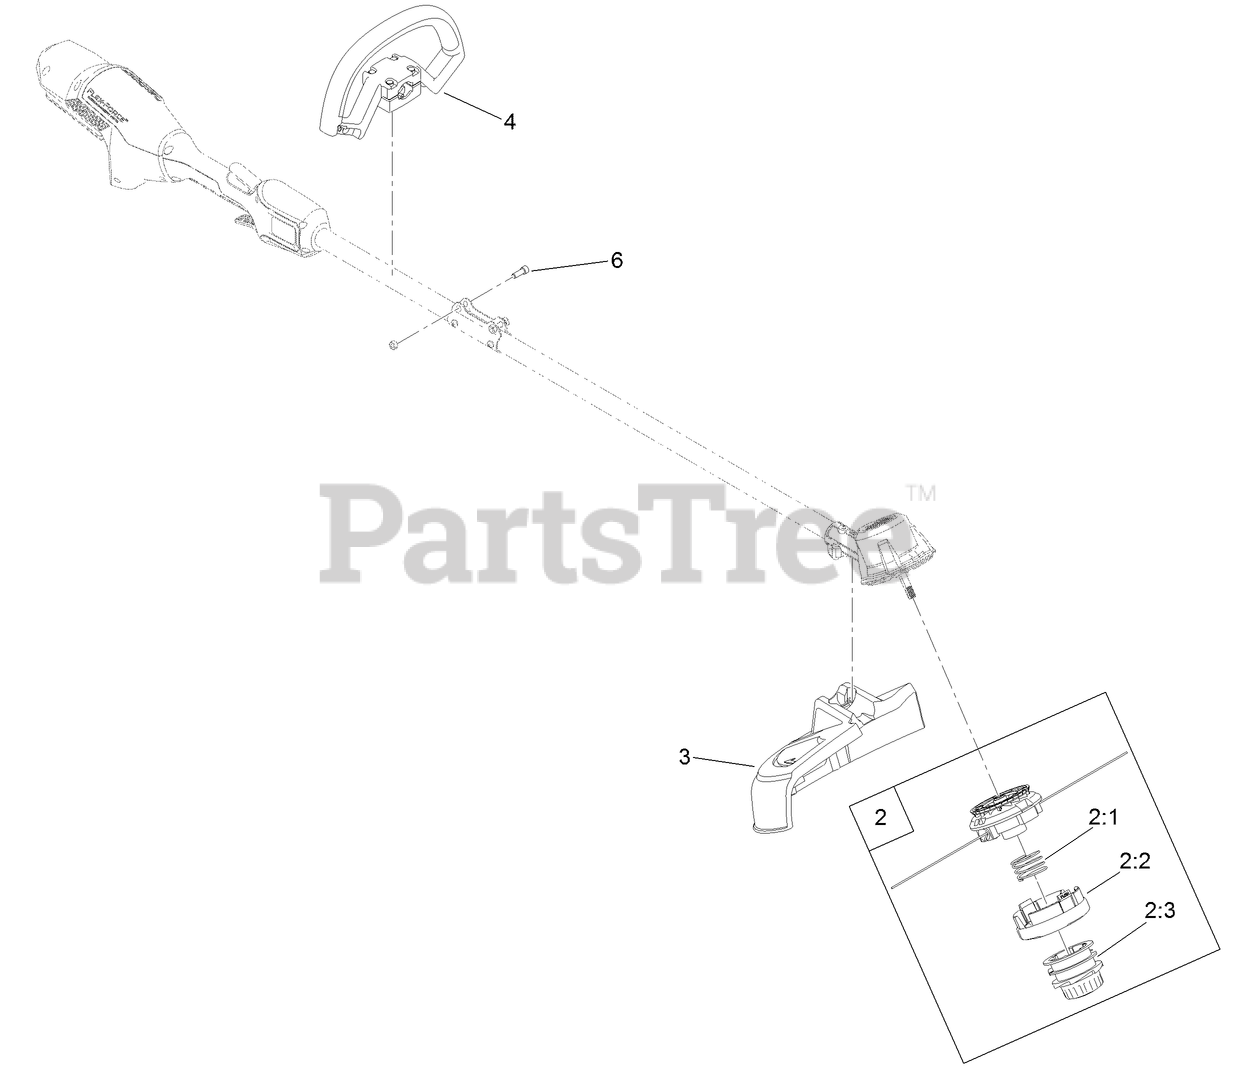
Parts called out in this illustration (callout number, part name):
2	BUMP FEED HEAD ASM
2:1	SPRING-SPOOL
2:2	CAP-FEED, BUMP
3	SHIELD-GRASS
4	HANDLE-TRIMMER
6	SCREW-HSH
